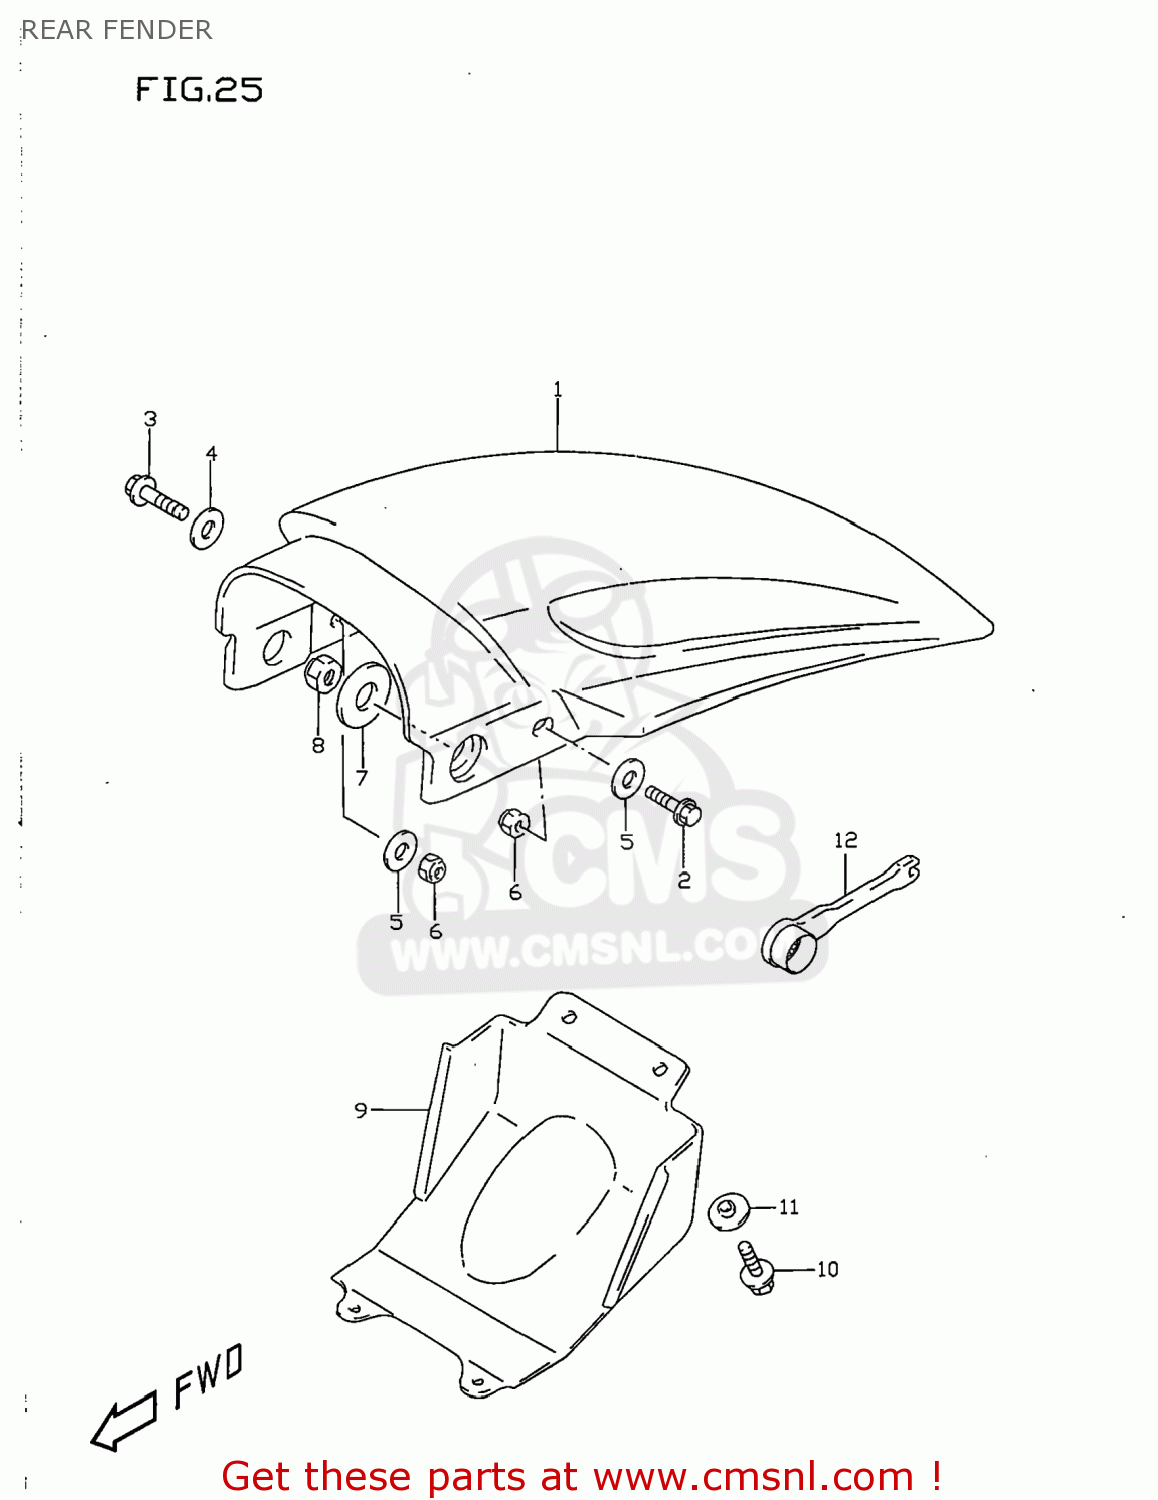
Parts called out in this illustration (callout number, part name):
1	FENDER,RR
2	BOLT
3	BOLT,G/S SWITC
4	WASHER(6.5X20X1.6)
5	WASHER(6.5X20X1.2)
6	NUT 6MM
7	WASHER(10.5X30X2.3)
8	NUT
9	MUDGUARD,RR FENDER FR
10	BOLT
11	WASHER
12	SPARK PLUG WRENCH 21 & SPANNER 5.1
